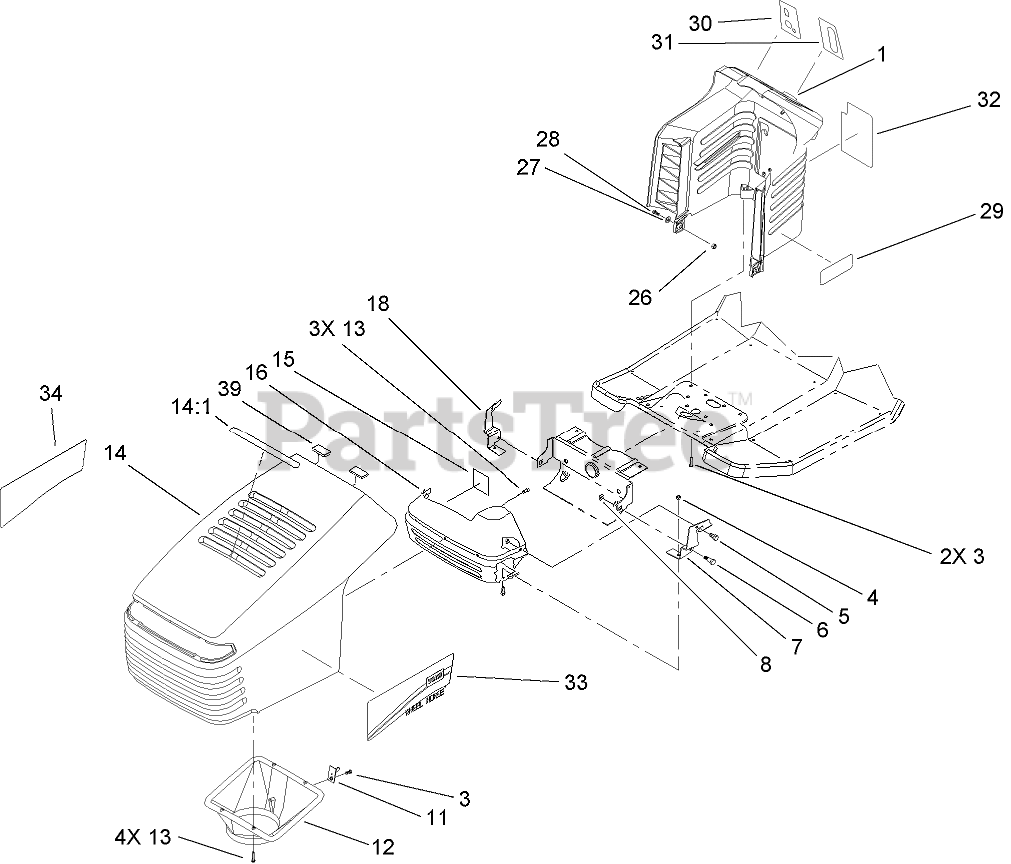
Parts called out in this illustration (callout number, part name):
1	TOWER-STEERING
3	SCREW-HWH
4	NUT-LOCK, NI
5	SCREW-HH
6	BOLT-SHOULDER
7	BRACKET-PIVOT, LH HOOD
8	NUT-RETAINER
11	LATCH-PIN
12	DUCT-AIR, HOOD
13	SCREW-PLASTITE
14	HOOD ASM
14:1	DECAL-AIR DUCT
15	TAPE-FOIL
16	SHIELD-HEAT
18	BRACKET-PIVOT, RH HOOD
26	NUT-LOCK, NI
27	WASHER-PLAIN
28	SCREW-HH
30	DECAL-IGNITION/LIGHTS
31	DECAL-THROTTLE/CHOKE
32	DECAL-DANGER
33	DECAL-HOOD
34	DECAL-HOOD
39	FOAM-HOOD
